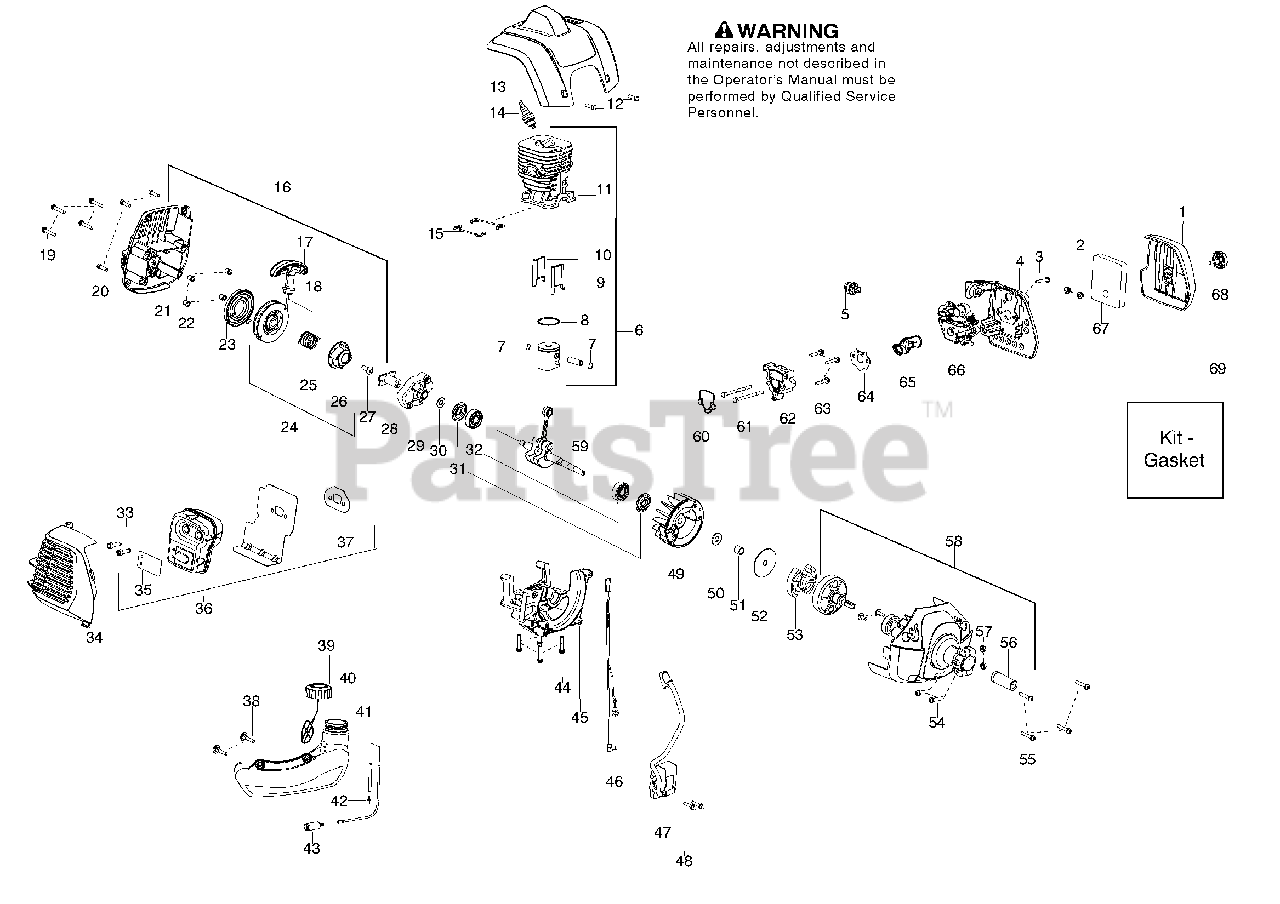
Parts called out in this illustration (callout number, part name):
2	Nut-Carb. Screw
6	Kit-Piston/Cyl.
7	Retainer-Piston pin
9	Insert-Front Transfer Port
10	Insert-Rear Transfer Port
11	Cylinder-Machined
12	Screw M4 x 1.75 x 16mm
14	Spark Plug (RCJ- 6Y)
15	Seal-Cylinder (Kit)
16	Assy-Shroud Rear
17	Handle-Starter
19	Screw M5 x 25mm
20	Screw M4 x 1.75
21	Housing-Starter w/eyelet
23	Kit-Starter Spring
24	Kit-Pulley
25	Spring-Starter Hub
28	Coupling-Starter
29	Assy-Starter Cup
31	Seal-Crankshaft (kit)
32	Bearing-Crankshaft
34	Guard-Muffler
35	Kit-Spark Arrestor
36	Assy-Muffler
37	Gasket-Muffler (kit)
38	Screw-Tank Retainer
39	Assy-Fuel Cap w/ret.
40	Assy-Tank
41	Kit-Fuel line
42	Fitting-Fuel Line
43	Assy-Fuel Pickup
44	Screw-m5x25mm
45	Assy-Crankcase
46	Assy-Leadwire
47	Module-Ignition
49	Assy-Flywheel
51	Spacer-Flywheel
52	Washer-Clutch
53	Kit-Clutch Assy.
54	Screw 10-24 x 1"
55	Screw M5 x 25mm
56	Guide-Clutch Drum
57	Locknut 10-24
58	Assy-Fan Hsg
59	Kit-Crankshaft
60	Seal-Cyl./Adapter (kit)
61	Bolt M5 x .80
62	Adaptor-Carburetor
63	Screw .20 x 32
64	Gasket-Carb./Adapter(kit)
66	Kit-Carburetor
68	Assy-Airbox Knob
69	Kit - Gasket
